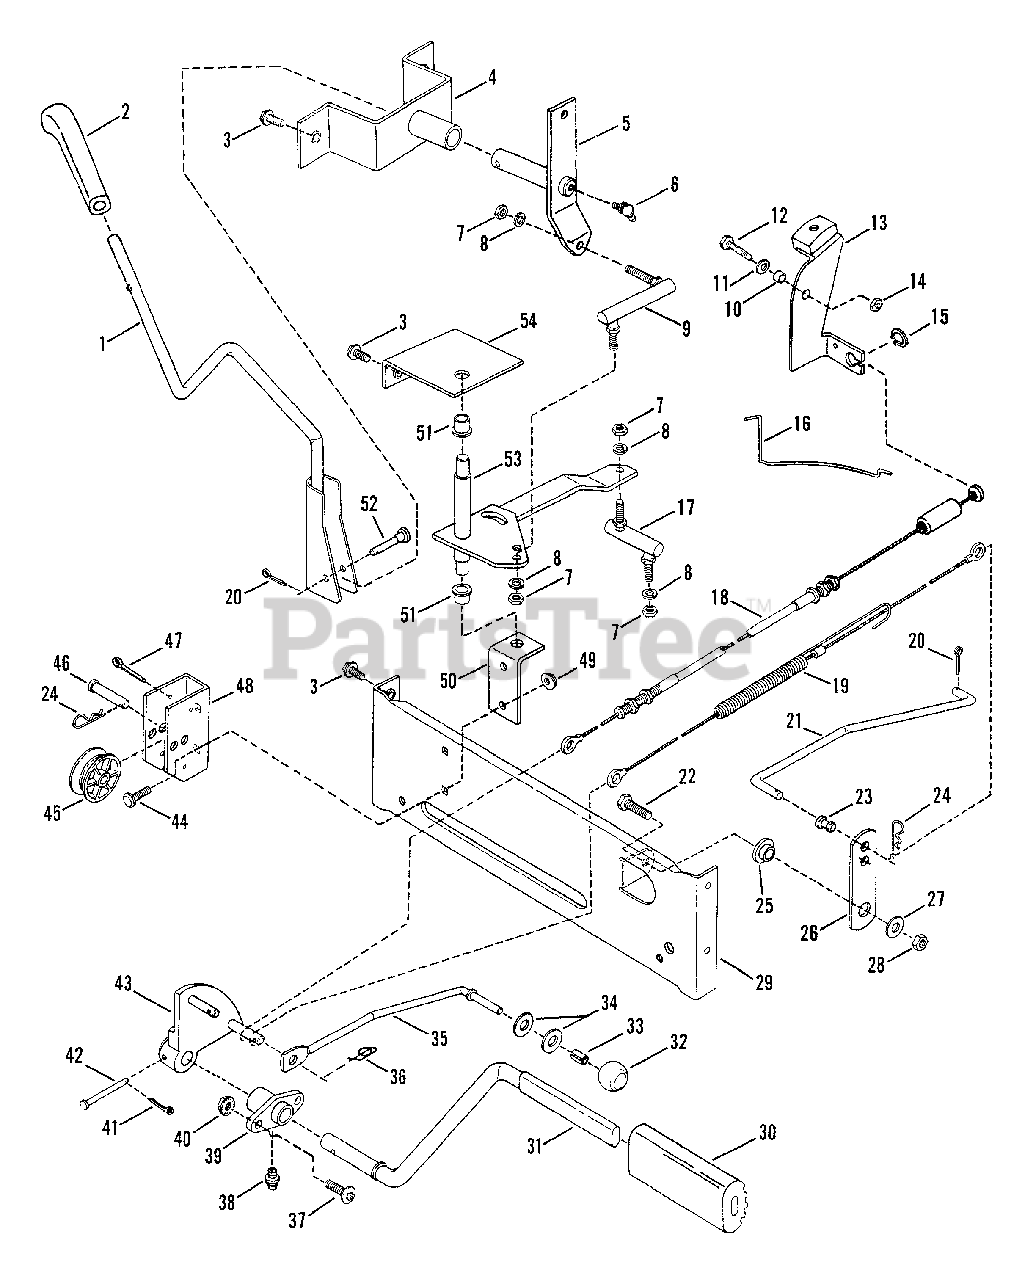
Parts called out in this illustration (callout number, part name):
1	SHIFTER, Transmission
2	KNOB, Shifter (Elongated)
3	SCREW, 5/16-18 x 1/2" Self-Tapping
4	PIVOT, Shifter
5	ASSEMBLY, Shifter Arm
6	FITTING, Lube
7	NUT, 5/16-24 Hex
8	WASHER, 5/16 Split Lock
9	LINK, Shift
10	SPACER
11	WASHER, 1/4 Flat
12	SCREW, 1/4-28 x 1" Hex Head Cap
13	ASSEMBLY, Brake Lever
14	NUT, 1/4-28 Hex Lock
15	RING, Retaining
16	SPRING, Brake Return
17	LINK, Shift
18	CABLE, Brake
19	CABLE, Clutch (23.5" Long)
20	PIN, 3/32 x 314" Cotter
21	ROD, Clutch
22	SCREW, 3/8-24 x 1" Hex Head Cap
23	BEARING, Nyliner
24	PIN, 1/4 Hair
25	SPACER
26	ARM, Pivot
27	WASHER, 3/8" Flat
28	NUT, 3/8-24 Hex Lock
29	BRACE
30	PAD, Pedal
31	PEDAL, Clutch/Brake
32	KNOB, Latch 5/16"
33	RING, Tolerance 5/16" x 1/2"
34	WASHER, 5/16 x 1-1/4" Flat Nylon
35	LATCH, Clutch/Brake
36	PIN, 3/64 x 1-7/32 Cotter (Self-Lock)
37	SCREW, 5/16-18 x 7/8" Truss Head (Torx)
38	FITTING, Lube 3/16"
39	PIVOT, Clutch/Brake Pedal
40	NUT, 5/16-18 Hex Flange Lock
41	PIN, 1/16 x 3/4" Cotter
42	PIN, 3/16 x 1 1/2" Clevis
43	BRACKET, Pedal Pivot
44	BOLT, 1/4-20 x 3/4" Short Neck Carriage
45	SPOOL, Bracket
46	PIN, 3/8 x 1 9/32" Clevis
47	PIN, 1/8 x 1 1/4" Cotter
48	BRACKET, Spool (Not available)
49	NUT, 1/4-20 Hex Flange Lock
50	BRACKET, Pivot
51	BEARING
52	PIN, 1/4 x 5/8" Clevis
53	LEVER, Shift
54	BRACKET, Shift
